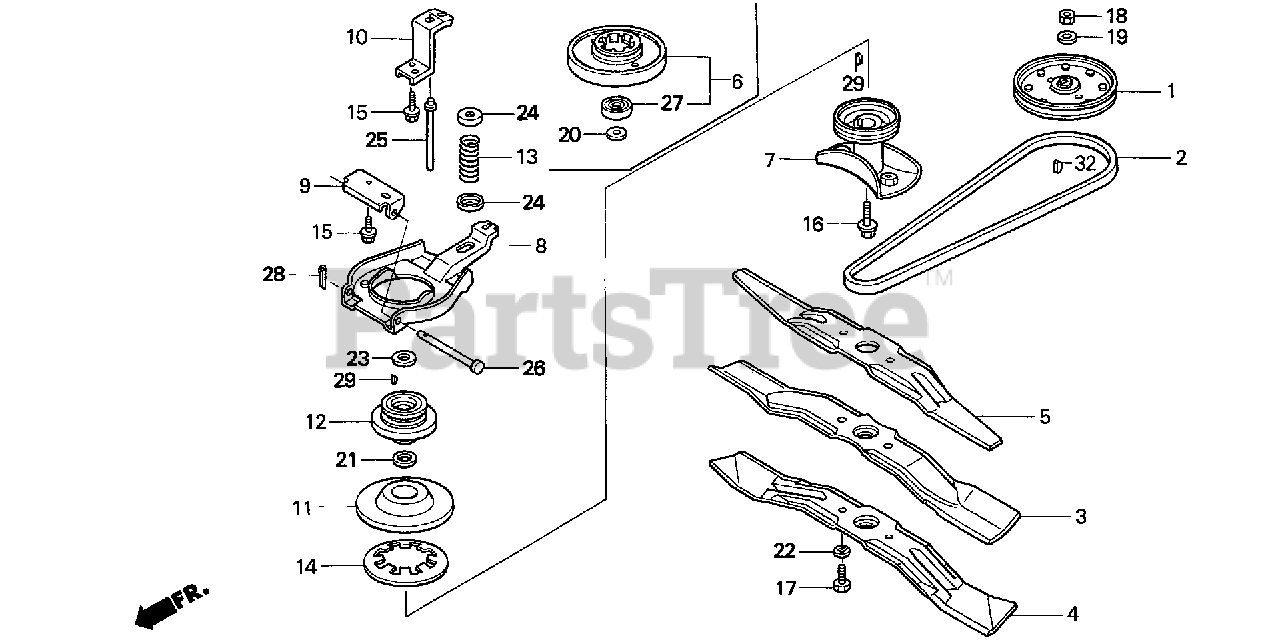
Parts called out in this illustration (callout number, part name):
1	PULLEY, DRIVEN
2	V-BELT (M-38)
3	BLADE, ROTARY (BAGGING)
3	BLADE, ROTARY
4	BLADE, ROTARY (PCD=88MM)
5	BLADE, ROTARY (UPPER)
5	BLADE, ROTARY (UPPER) (PCD=88MM)
6	HOLDER ASSY., BLADE
8	ARM, BRAKE
8	ARM, BRAKE (91MM)
9	HINGE, CLUTCH ARM
10	HOLDER, CLUTCH RETURN SPRING
11	DISK, DRIVEN
12	PULLEY KIT
12	DRIVE PULLEY KIT
13	SPRING, CLUTCH RETURN
14	SPRING, CLUTCH
15	BOLT, FLANGE (6X14) (CT200)
16	BOLT, HEX. (10X25)
17	BOLT, HEX. (10X20)
18	NUT, U (10MM)
20	WASHER (10MM)
21	WASHER, THRUST (20X30X1.5)
22	WASHER, SPRING (10MM)
23	WASHER, THRUST
24	WASHER, SPECIAL (10MM)
25	PIN, SPRING GUIDE
26	PIN, HOOD HINGE
27	BEARING, RADIAL BALL (6204)
28	PIN, SPLIT (2.0X15)
29	KEY, WOODRUFF (16X15)
32	KEY, WOODRUFF
